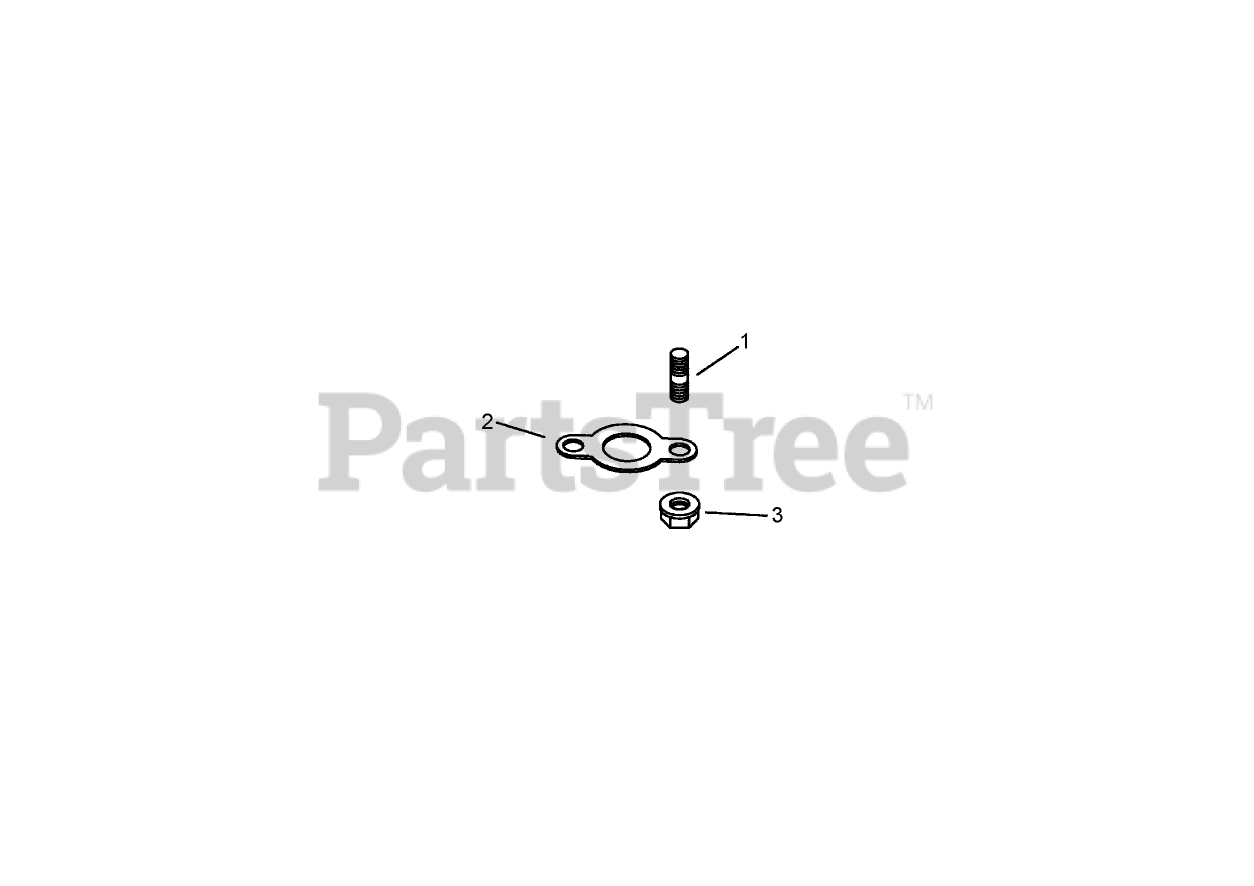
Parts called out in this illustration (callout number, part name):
1	STUD (M8X1.25X33)
2	GASKET-EXHAUST
3	NUT-FLANGE (M8X1.25)
